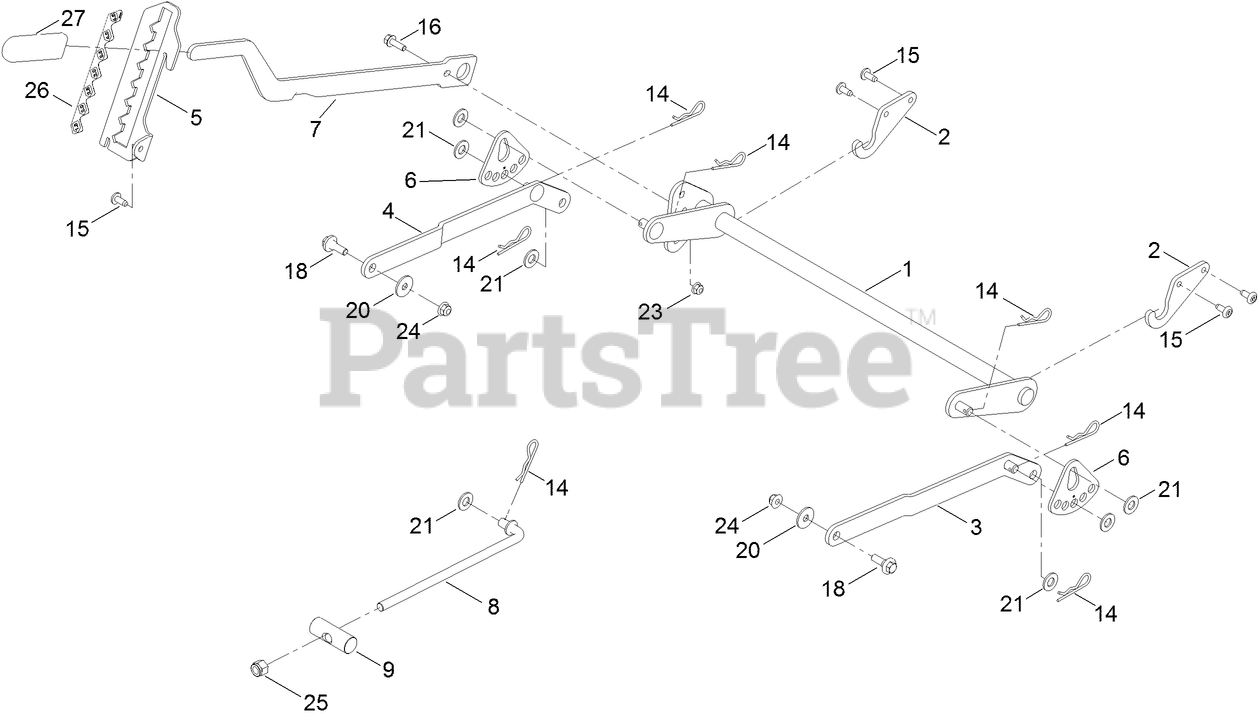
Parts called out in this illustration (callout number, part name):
1	DECK LIFT ASM
2	BRACKET-PIVOT, DECKLIFT
3	LH ARM ASM
4	RH ARM ASM
5	BRACKET-HOC
6	PLATE-ADJUSTMENT, HOC
7	LEVER-LIFT
8	ROD-MOUNT, DECK
9	PIN-PIVOT
14	PIN-COTTER
16	SCREW-HHF
18	SCREW-SHOULDER
20	WASHER-HARDENED
21	WASHER-FLAT
23	NUT-HF, NI
24	NUT-HF, NI
25	NUT-HEX
26	DECAL-HOC
27	GRIP-LEVER
